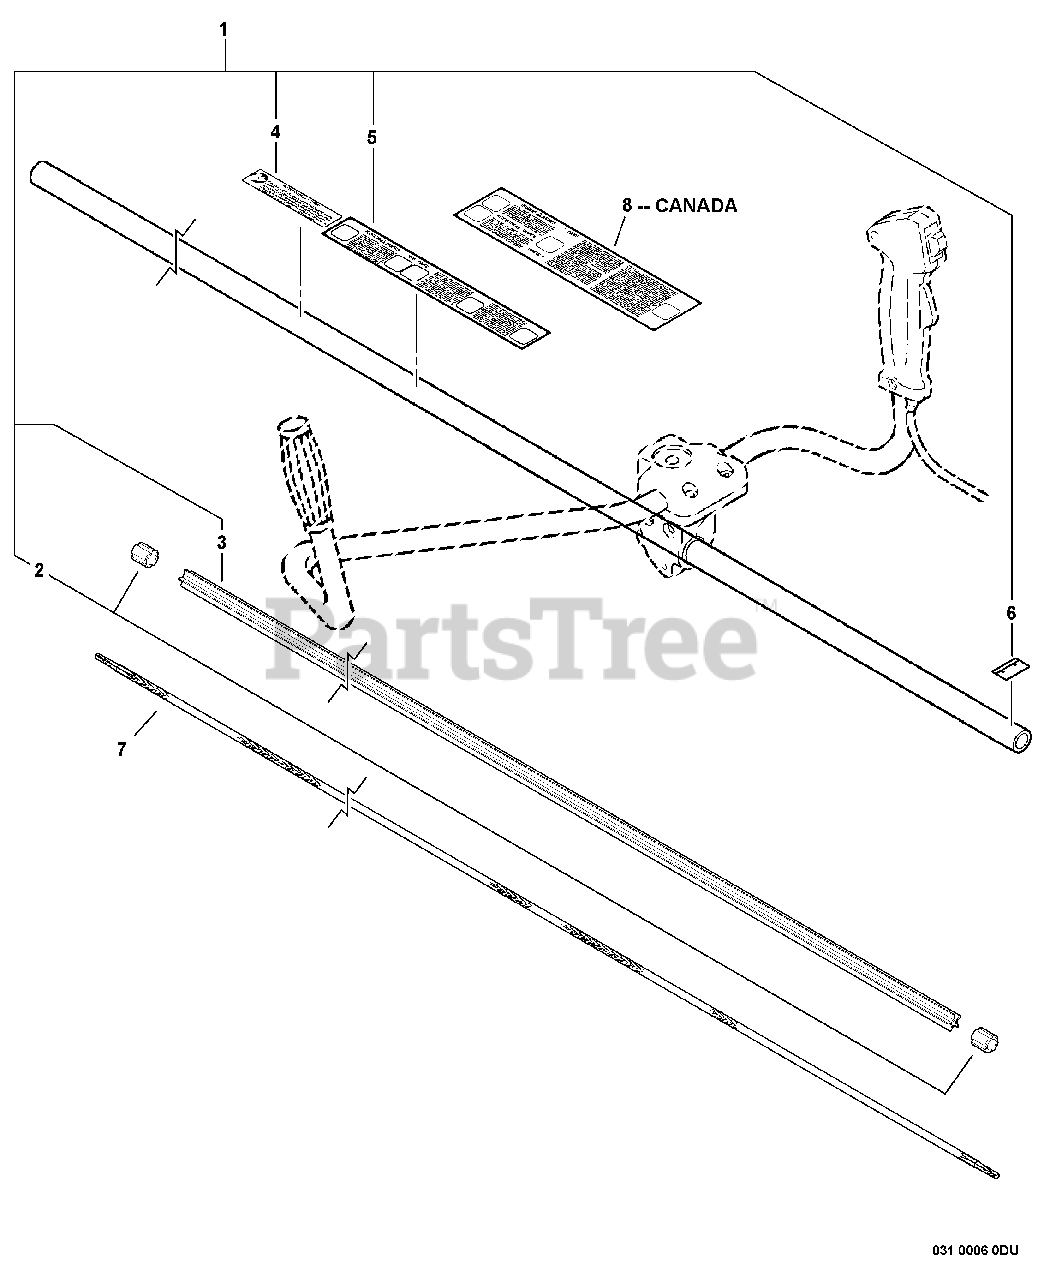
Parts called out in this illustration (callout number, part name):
1	MAIN PIPE ASSY
3	LINER - FLEXIBLE
4	LABEL - CAUTION -- SPANISH
5	LABEL - CAUTION
6	LABEL - ALIGNMENT
7	DRIVESHAFT - FLEXIBLE
8	LABEL - CAUTION
